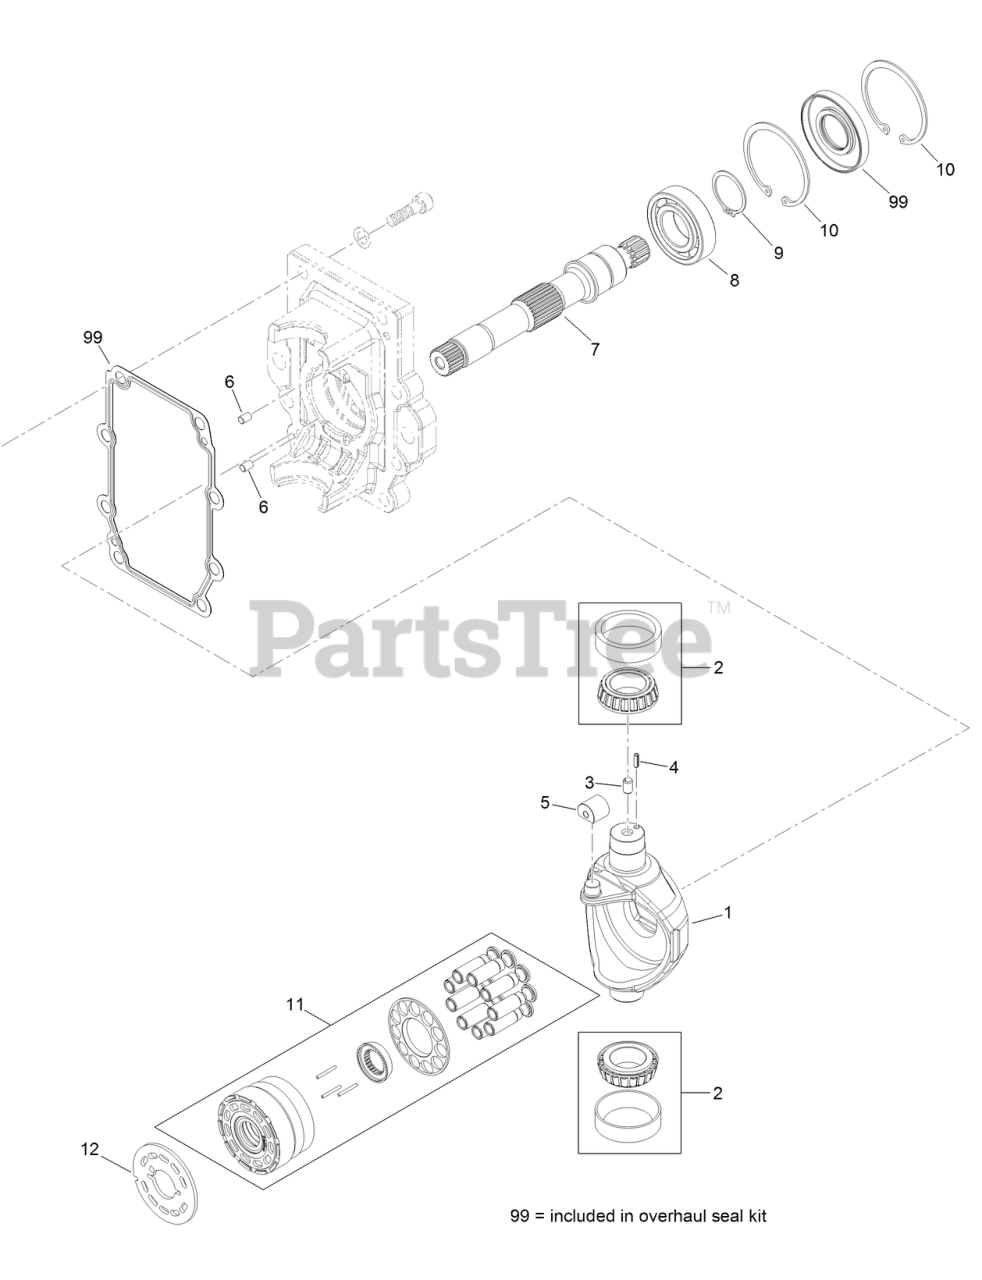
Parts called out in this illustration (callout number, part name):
1	SWASHPLATE
2	BEARING-ROLLER
3	BUSHING
4	PIN-SLOTTED
5	BLOCK-SLIDER
7	SHAFT-13TOOTH
8	BEARING-BALL
9	RING-RETAINING
10	RING-RETAINING
11	CYLINDER BLOCK KIT
12	PLATE-VALVE
99	SEAL KIT
